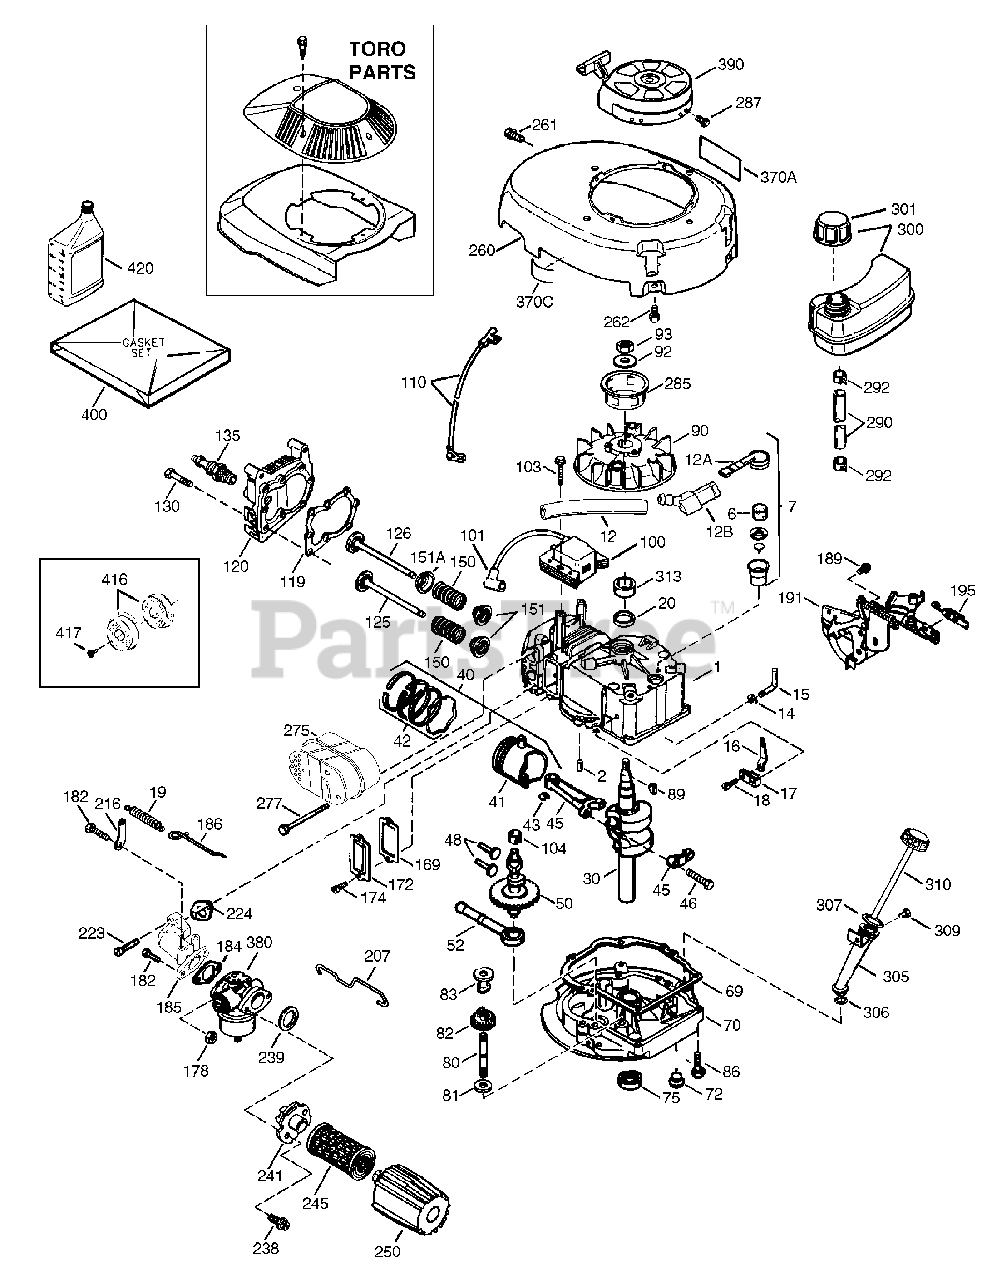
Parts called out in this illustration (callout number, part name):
1	Cylinder (Incl. 2,20 & 150)
2	Dowel Pin
6	Element-Element
7	Breather Body ASM(Incl. 6 & 12A)
12	Breather Tube
12A	Breather Cover & Tube
12B	Breather Tube Elbow
14	Washer
15	Governor Rod(Incl. 14)
16	Governor Lever
17	Clamp, Governor
18	Screw
19	Grip-Foot Pedal
20	&al, Oil
30	Crankshaft
40	Piston, Pin & Ring Set(Std.)
41	Piston & Pin ASM(Std.)(Incl. 43)
41	Piston & Pin ASM(.010" OS)(Incl. 43)
41	Piston & Pin ASM(.020" OS)(Incl. 43)
42	FITTING - TANK 3/4"
42	FITTING - TANK 1"
43	Ring-Retaining
45	Connecting Rod ASM(Incl. 46)
46	Screw
48	Lifter Valve
50	Camshaft
52	Oil Pump ASM
69	Mounting FlangeGasket
70	Mounting Flange(Incl. 72 thru 83, 306)
72	Plug-Oil
75	Oil Seal
80	Governor Shaft
81	Washer
82	Governor Gear ASM(Incl. 81)
83	Spool-Govemor
86	Screw
89	THROTTLE TRIGGER ASM
90	Flywheel
92	Washer
93	Flywheel Nut
100	Solid State Ignition
101	Cover Spark Plug
103	Screw
104	Cam Bushing
110	Ground Wire
119	Cylinder Head Gasket
120	Cylinder Head
125	Exhaust Valve (Std.)(Incl. 151)
126	Intake Valve (Std.)(Incl. 151)
130	Screw
135	Spark Plug (RJ19LM)
150	Spring Valve
151	Cap-Valve Spring
151A	BEARING - TRANS
169	Valve Cover Gasket
172	Valve Cover
174	Screw
178	Nut
182	Screw
184	Gasket-Carburetor
185	Intake Pipe
186	Governor Link
189	Screw
191	S.E. Brake Bracket(Incl. 195)
195	Terminal
207	Link-Throttle
216	Lever, RPM Adjusting
223	Screw
224	Intake Pipe Gasket
238	Screw
239	Air Cleaner Gasket
241	Air Cleaner Collar
245	Air Cleaner Filter
250	Air Cleaner Cover
260	Blower Housing
261	Screw
262	Screw
263A	Starter Grill
275	Muffler
277	Screw
285	Starter Cup
287	Screw
290	Fuel Line
292	Clamp Fuel Line
298	Screw
300	Fuel Tank(Incl. 292 & 301)
301	Cap Fuel
305	Tube Fill
306	"O"-Ring
307	O-Ring
309	Screw
310	Dipstick
313	Spacer
370A	Decal-Instruction
370C	Primer Decal (3X)
370D	Caution Decal
370K	Emblem Decal
380	Carburetor (Incl. 184)
390	Rewind Starter
400	Gasket Set
416	Spark Arrestor Kit (Incl. 417)(Optional)
417	Screw
420	SAE30 4-Cycle Engine Oil (Quart)
